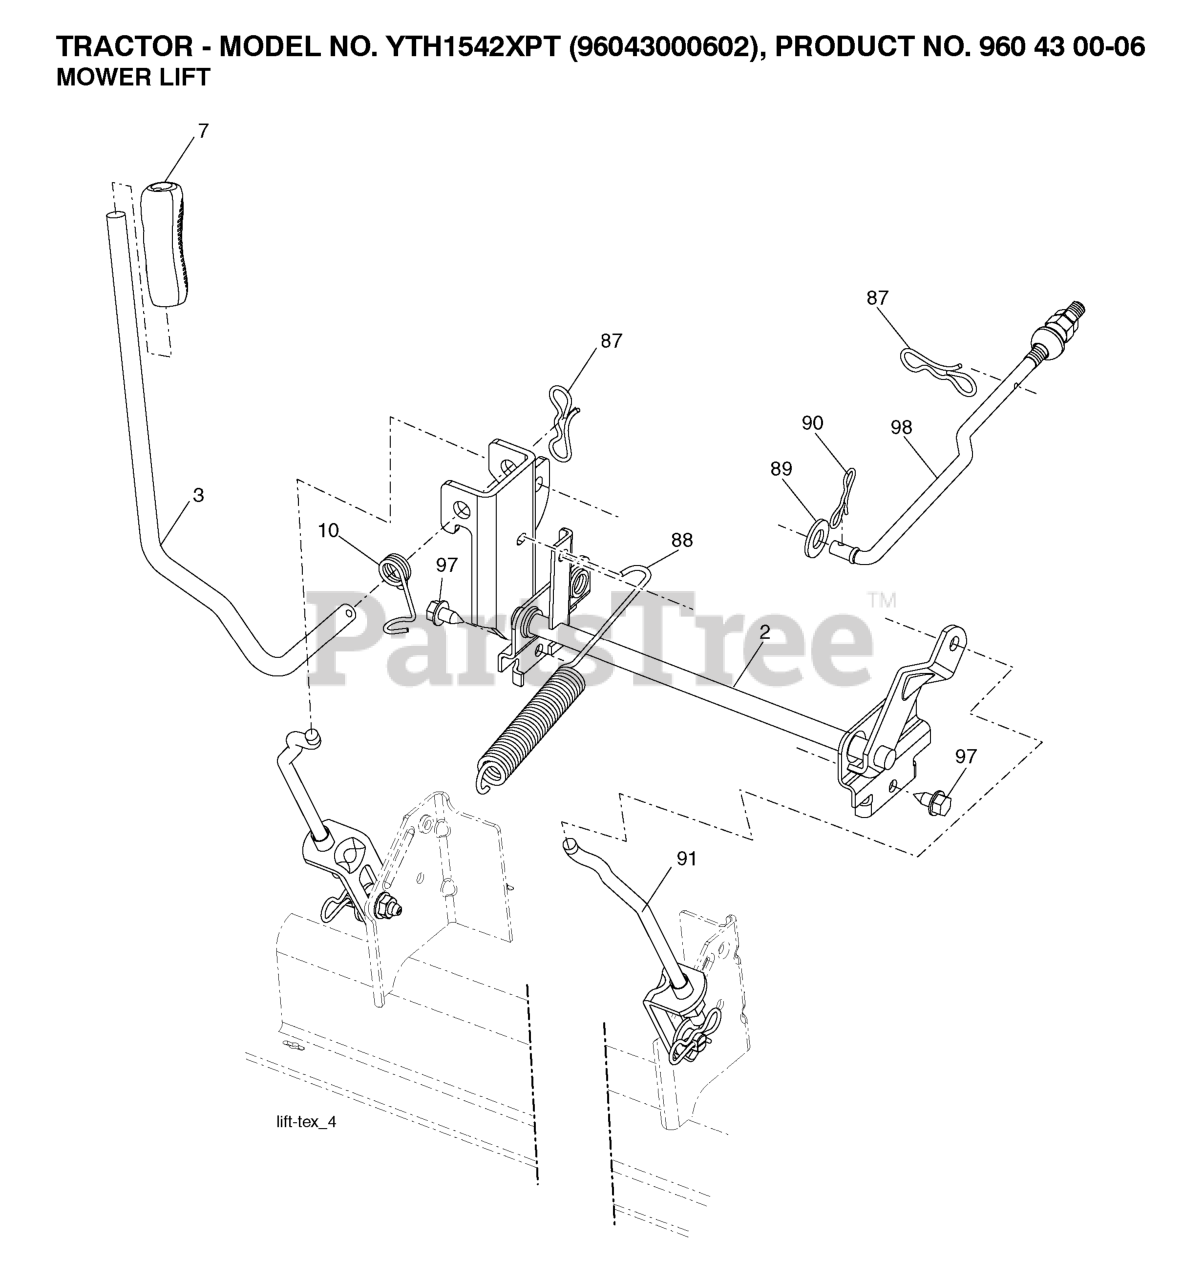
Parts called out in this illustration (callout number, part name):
2	SHAFT.ASM.LIFT.CROSS.H
3	LEVER.LIFT.HANDLE.GT
7	GRIP.LEVER.5625.ID
10	SPRING.TORSION.LIFT.HANDLE
87	PIN.COTTER.7/16.BOW TI.
88	SPRING.LIFT.ASSIST.GT2
89	WASHER.CLEAR.ZINC
90	PIN.COTTER.5/16.BOW TI
91	LINK.ASM.LIFT.REAR
97	SCREW 3/8-16X3/4
98	LINK.ASM.SUSP.FRONT.MW
